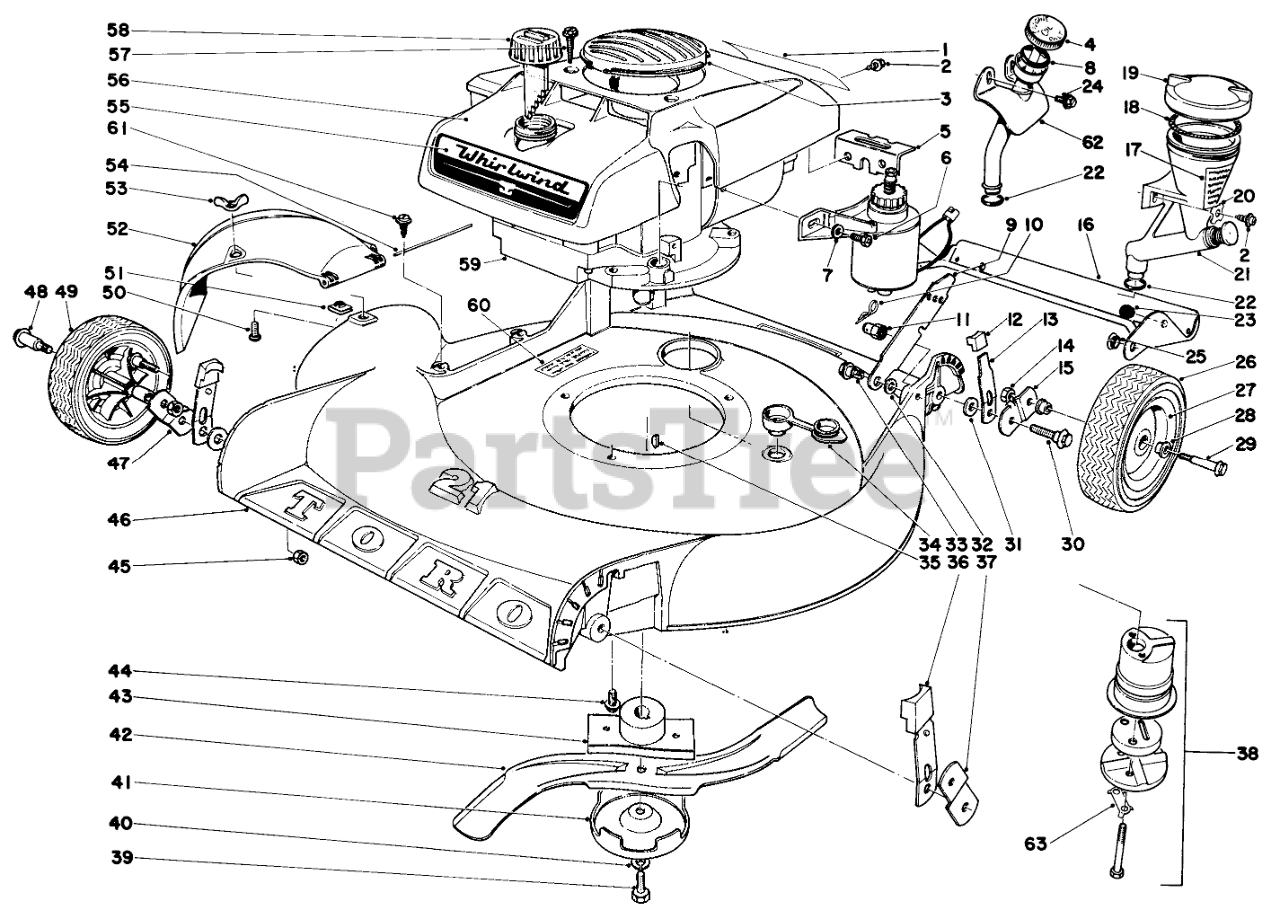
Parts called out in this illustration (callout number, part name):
1	Decal,Maintenance
2	Screw
3	Insert Shroud
4	Dipstick
5	Bracket
6	SCREW-HH
7	WASHER-FLAT
8	O-Ring
9	Latch
10	PIN-COTTER, HAIR
11	Nut
13	Spring Arm
14	Nut
15	Pivot Arm
16	Safety Shield, Rear
17	Decal, Reservoir
18	"O" Ring
19	Cap, Reservoir (Incl. Ref. 18)(Used on Model #19225)
20	Washer
21	Reservoir, Oil
22	O-RING
23	SKID BUTTON
25	Nyliner
26	8 TIRE
27	Wheel Assy. (Incl. Ref. #28)
28	Bushing
29	Wheel Bolt
30	Pivot Screw
31	WASHER-PIVOT
32	SPACER
33	SCREW-SHOULDER
34	Washer Plug
35	KEY-WOODRUFF
36	ARM KNOB
37	Pivot Arm
38	MUFFLER KIT
39	SPECIAL SCREW
40	WASHER-LOCK
41	ANTI-SCALP CUP
42	Blade
43	BLADE RETAINER WA
44	Screw
45	Nut
46	Housing
47	Pivot Arm
51	NUT-SPEED
52	Deflector
53	NUT-WING SPECL
54	HINGE PIN
55	Decal
56	Shroud
57	SCREW-HWH
58	Gas Cap
59	Engine (Used on Model 19444)
60	Decal
61	SCREW-HWHTF
62	Oiler Tube
63	CLIP - LOCKING
